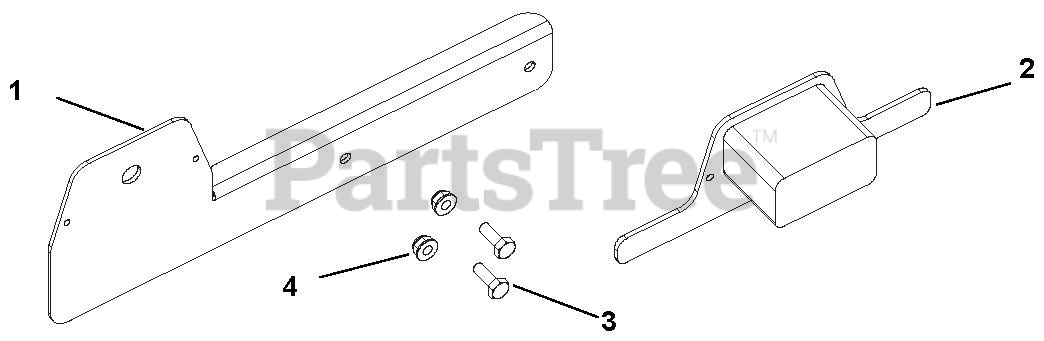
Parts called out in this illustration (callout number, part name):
1	Bracket, License Plate
2	Light
3	Bolt, Hex .25-20 x .75
4	Nut, Nyloc Flange .25-20
